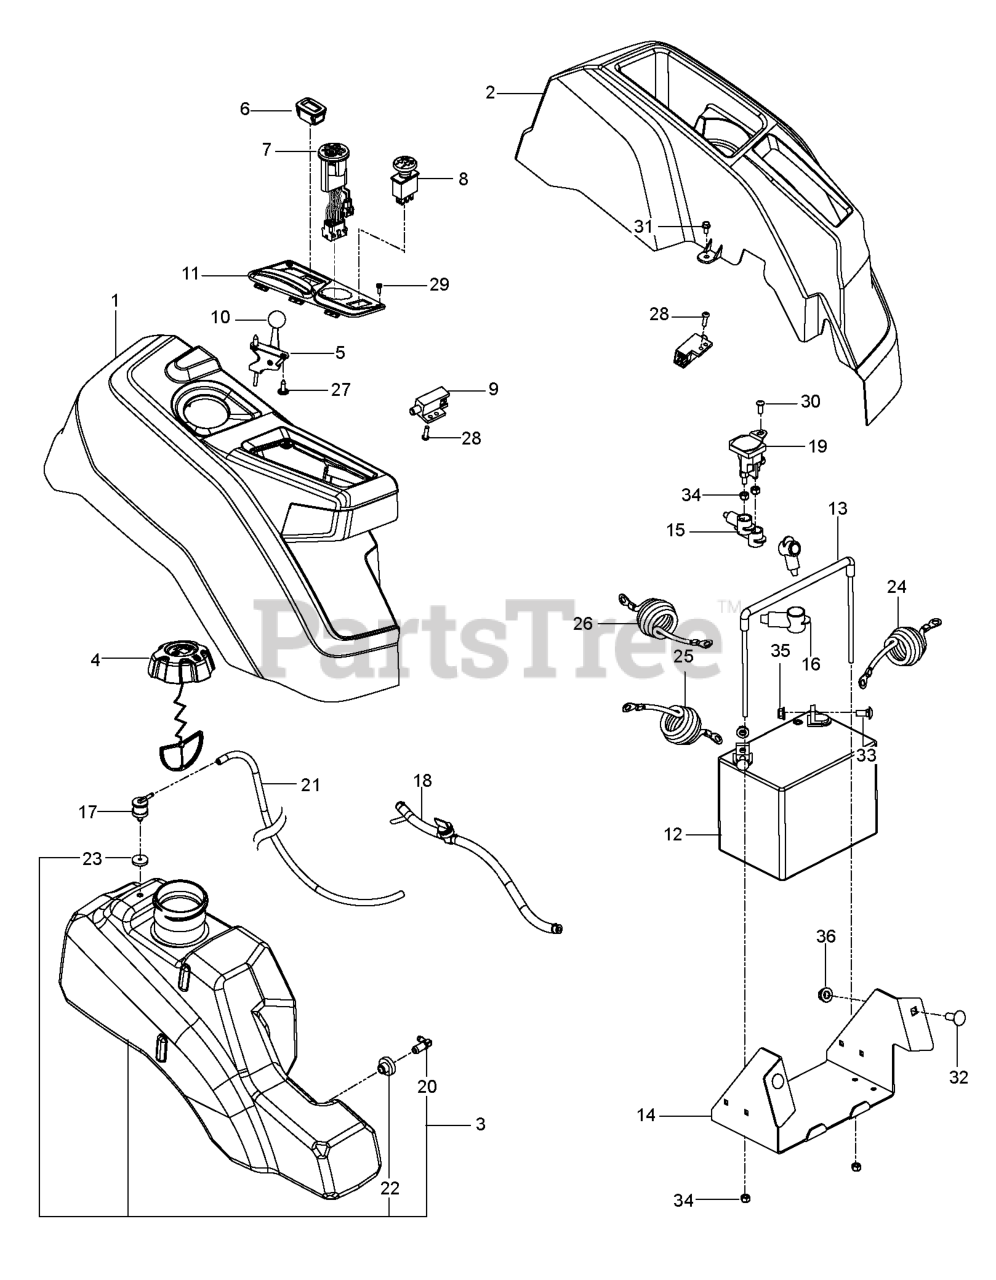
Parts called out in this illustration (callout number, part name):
2	KEY 1/4 X 2.5
7	HUB.PNT.GT.PM.1IN.AXLE.E-DIP
15	WASHER
17	SPRING.BRAKE.HG3000/3500
26	SPRING.RETURN.CRUISE
33	E RING HYT
35	ROD .BRAKE. PARKING. GT. HUSQ.
42	PEDAL COVER T
48	BOLT.3/8-16X1.50
50	IDLER.FLAT.910.OFFSET
51	NUT LOCK FLG 3/8-16 UNC
52	IDLER.V-GROOVE.910.OFFSET
56	V-BELT.GROUND.DRIVE.
64	SHAFT.ASM.PEDAL.BRK.CNTR
70	CONSOLE.ASM.RH.GT.FC.HUSQ
73	BOLT HEX FLGHD 5/16-18X3 GR. 5
74	SCREW.HI-LO.CONSOLE
80	STRAP.TORQUE.YT.G700
92	BOLT
99	SPRING.BYPASS.YT.G700
114	NUT.71038.31-18.HEX.NYLOCK
116	NUT LOCK HEX FLANGE 5/16-18
121	BRACKET STRAP TORQUE
125	SCREW
145	WASHER.AXLE.FLANGE.HG-3000
153	RETAINER M
159	COTTER PIN
160	RETAINER CLIP
161	SPRING, RETURN LT
163	ROD PEDAL CONTROL
166	NUT.PUSH.625
167	LATCH.BRAKE.SPRING
183	SPACER.SPLIT.1.000ID X 1.500
184	HANDLE.PARKING.BRAKE.H (BLK)
186	SPACER.RETAINER
187	WASHER 12/32X2X10GA
188	LINK.CLUTCH.GROUND DRIVE.LONG
189	BELLCRANK.GROUND.DRIVE.TRAPPED
190	KEEPER BELLCRANK ROUND DRIVE
196	SCREW 3/8-16X1
197	BRKT.ANIT-ROTATION.CLUTCH
203	WASHER
206	BRACKET.MOUNT.CRUISE.LATCH
207	LATCH.CONTROL.CRUISE.TEX
208	GEAR.SECTOR.CONTROL.CR
209	ROD.CONTROL.CRUISE.GT.
210	ROCKER.ASM.PEDAL.CONTR
211	BEARING.NYLON
213	KNOB.CONTROL.CRUSIE.HU
214	PEDAL.FORWARD.HUSQVARNA.DEALER
215	PEDAL.COVER.REVERSE.CRD.X428BK
220	REFLECTOR.RH.TEX GT
221	RETAINER.SPRING.CLIP.H
222	WASHER 21/32 X 1-1/4 X 10 GA.
284	NUT.U-CHNL.1/4-20.550DP.350PNL
286	BOLT.5/16-18X2.5
306	PIN COTTER
307	SCREW.MACHINE.CR.1/4-20
323	SLEEVE.BELLCRANK
